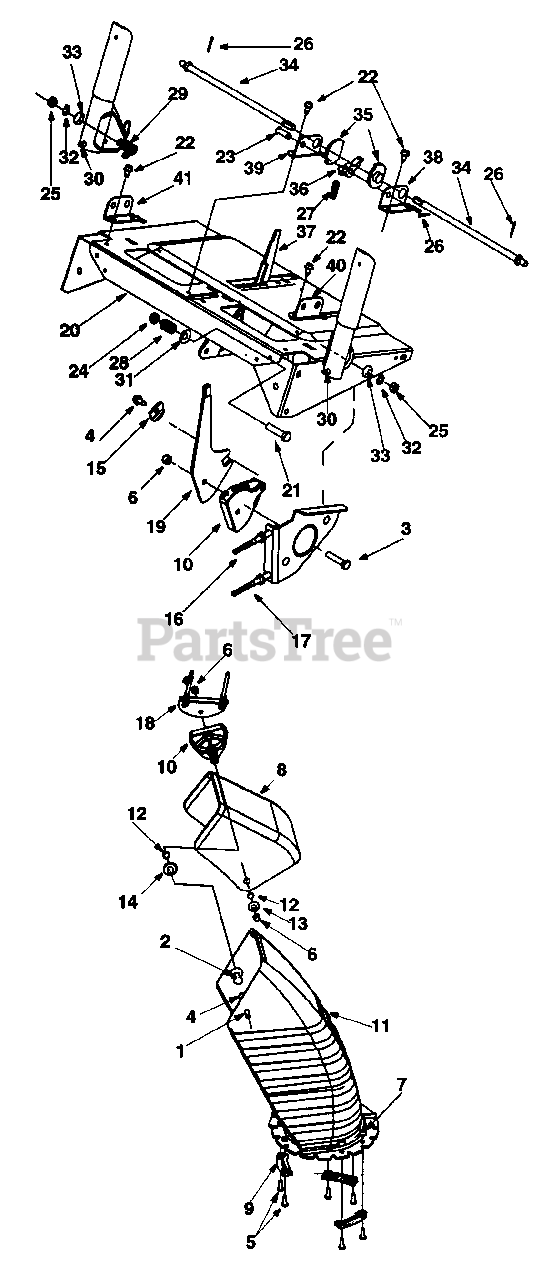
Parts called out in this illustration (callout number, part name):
1	Carriage Screw
2	Carriage Bolt 5/16-18 x 1.75"
3	Hex Bolt 5/16-18 x 1.5"
4	Hex AB Screw 1/4-14 x .625"
5	Hex Screw 1/4-20 x .75"
6	Hex Lock Nut
7	Hex Flange Lock Nut
8	Upper Chute
9	Chute Flange Keeper
10	Cable Guide: Chute Tilt
11	Lower Chute
12	Spacer
15	Special Washer
16	Chute Control Cable
17	Chute Cable w/Clip
20	Handle Panel Assembly w/ Tilt
21	Hex Bolt 3/8-24 x 1.5"
22	TT Screw 1/4-20 x 0.5"
29	Torsion Spring
30	Rubber Bumper
32	Lock Washer
33	Special Washer
35	Cam: Handle Lock
36	Pawl: Handle Lock
